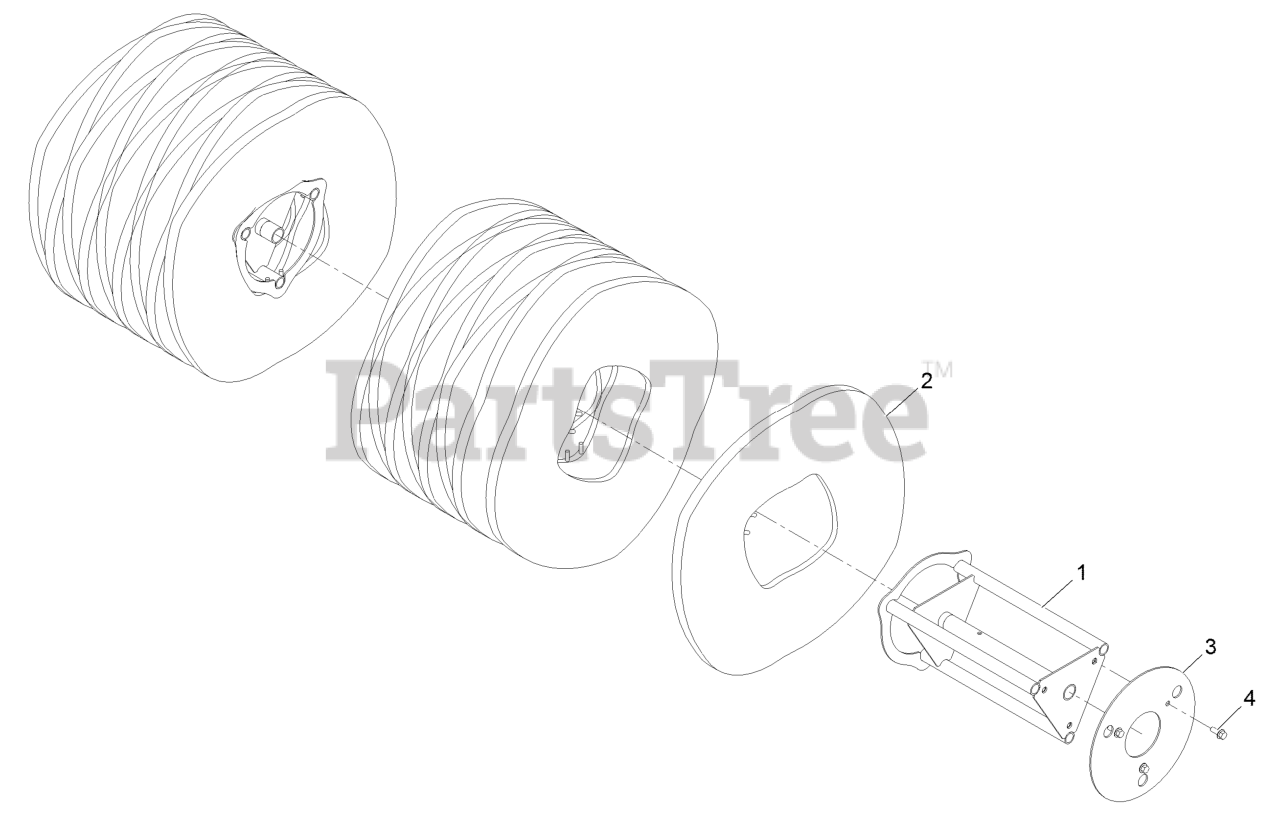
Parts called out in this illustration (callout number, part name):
1	Core-Broom
2	Segment-Poly
3	Plate-End, Retainer
4	Screw-HH Flg 3/8-16 X 1
